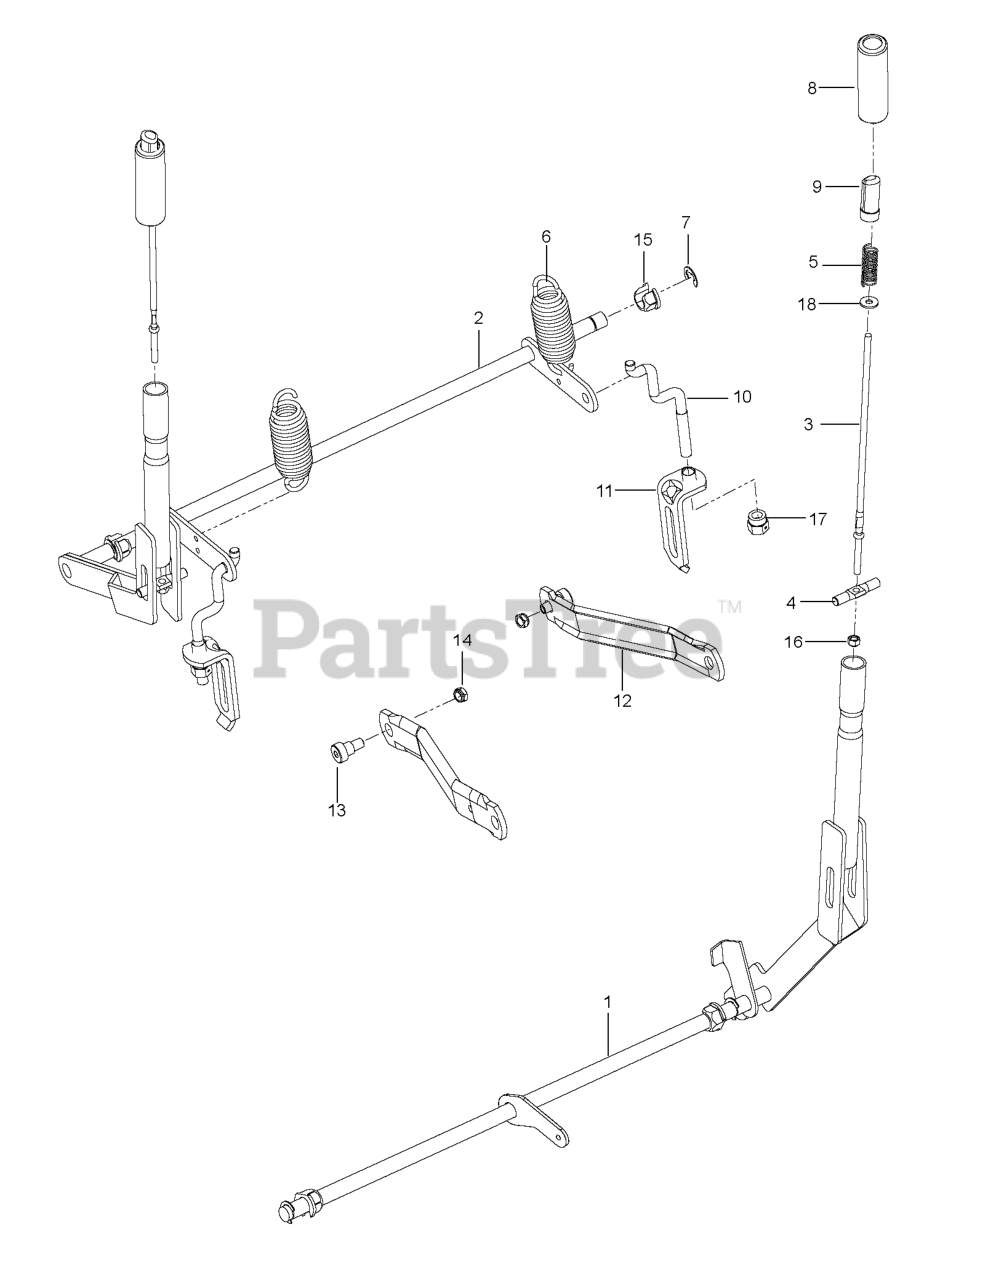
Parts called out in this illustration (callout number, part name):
1	SUBASM.SHAFT.BRAKE.WLDMNT.MED
2	DECK.LIFT.PNT.WELDMENT.RZ.BLK
3	ROD, HANDLE RELEASE
4	RB ROD, LATCH RELEASE
5	SPRING, COMPRESSION
7	E-RING 5/8
8	GRIP, HANDLE, BLACK 4"
9	BUTTON, PUSH, BLACK
10	LINK, REAR SUSPENSION
11	ASSEMBLY, BRKT LINK
12	ARM.SUSPENSION.MOWER
13	SB 3/8-16 X 3/8 SKT HD ZD
14	NUT HEX 3/8-16 NYLON, THIN
15	PLASTIC NUT
16	LOCKNUT.NYLOC.1/4-20
17	NUT, LIFT LINK 7/16-20
